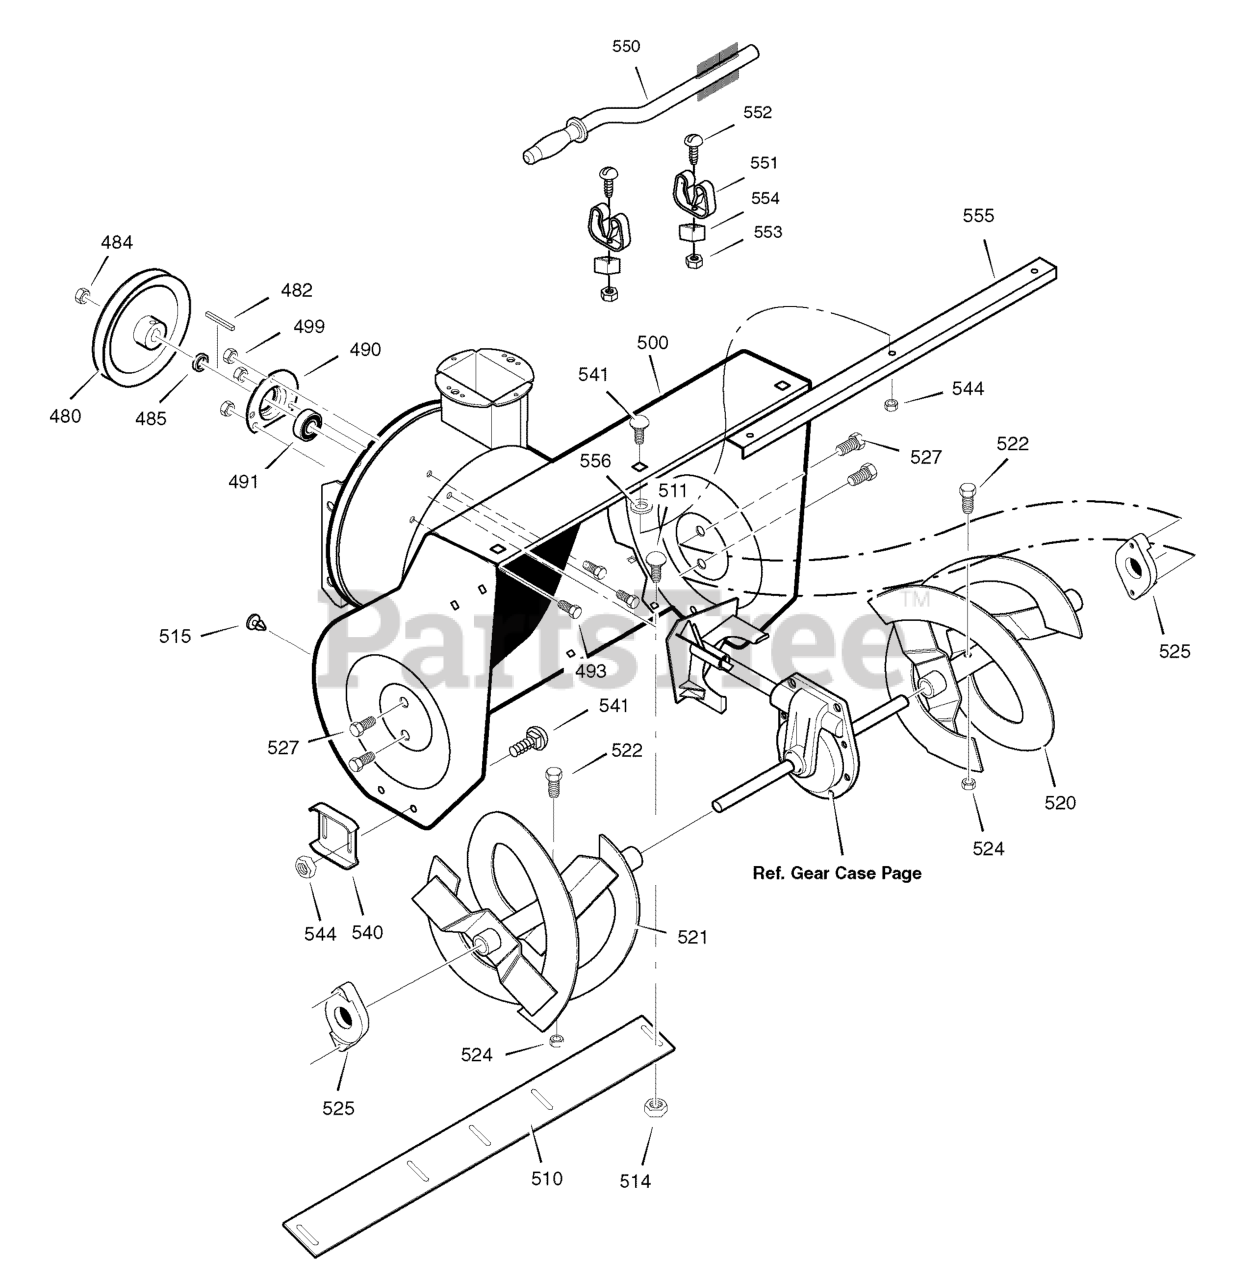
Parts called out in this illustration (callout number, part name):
480	PULLEY, 4L 8.40 OD
482	KEY, SQUARE 3/16 X 3/4
484	NUT, 1/2-20
485	SPACER, FRICTION PULLEY
490	RETAINER, BALL BEARING
491	BEARING, BALL
493	BOLT, HEX 5/16-18 X 0.62
499	NUT, 5/16-18 HEXWDFLLK
500	HOUSING, ASSEMBLY
510	BLADE, SCRAPER
511	BOLT, 5/16-18 X 0.75
514	NUT, 5/16-18
515	PLUG PANEL, BLACK
520	AUGER, ASSEMBLY, LH
521	AUGER, ASSEMBLY, RH
522	SCREW, 5/16-18 X 1.75
524	NUT, 5/16-18
525	BEARING, FLANGE
527	SCREW, 5/16-18 x 0.75
540	SKID, HEIGHT ADJUST
541	BOLT, 5/16-18 X 0.75
544	NUT, 5/16-18
550	BRUSH, CLEANOUT
551	CLIP, RETAINER
552	SCREW
553	NUT
555	STIFFENER
556	WASHER
